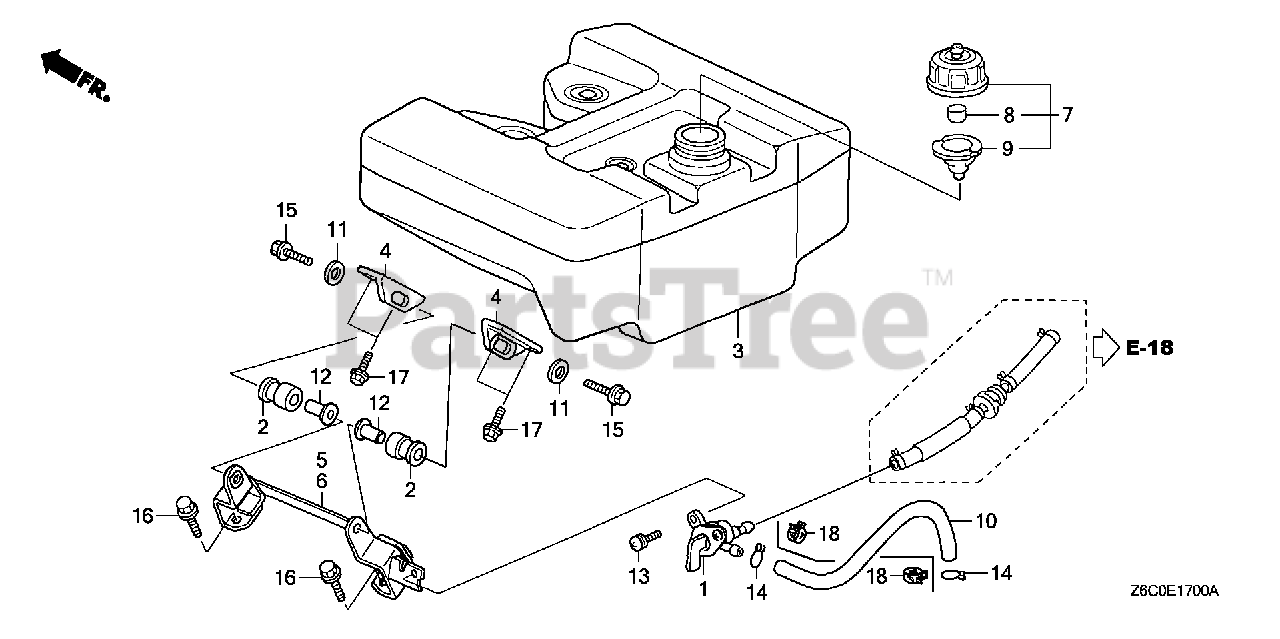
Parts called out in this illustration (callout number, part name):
1	PETCOCK ASSY.
2	RUBBER, TANK MOUNTING
3	TANK COMP., FUEL
3	TANK, FUEL
4	BRACKET, FUEL TANK
5	STAY, R. FUEL TANK
6	STAY, L. FUEL TANK
7	CAP ASSY., FUEL TANK
8	SPONGE, FUEL CAP BREATHER
9	GASKET, FUEL CAP
10	TUBE A, FUEL (FKM)
11	WASHER, PLAIN (6MM)
12	COLLAR, TANK SETTING
13	SCREW-WASHER (5X14)
15	BOLT, FLANGE (6X45)
16	BOLT, FLANGE (8X20) Use up to Engine SN 1609606.
17	BOLT, FLANGE (6X16)
18	CLIP, TUBE (D8)
